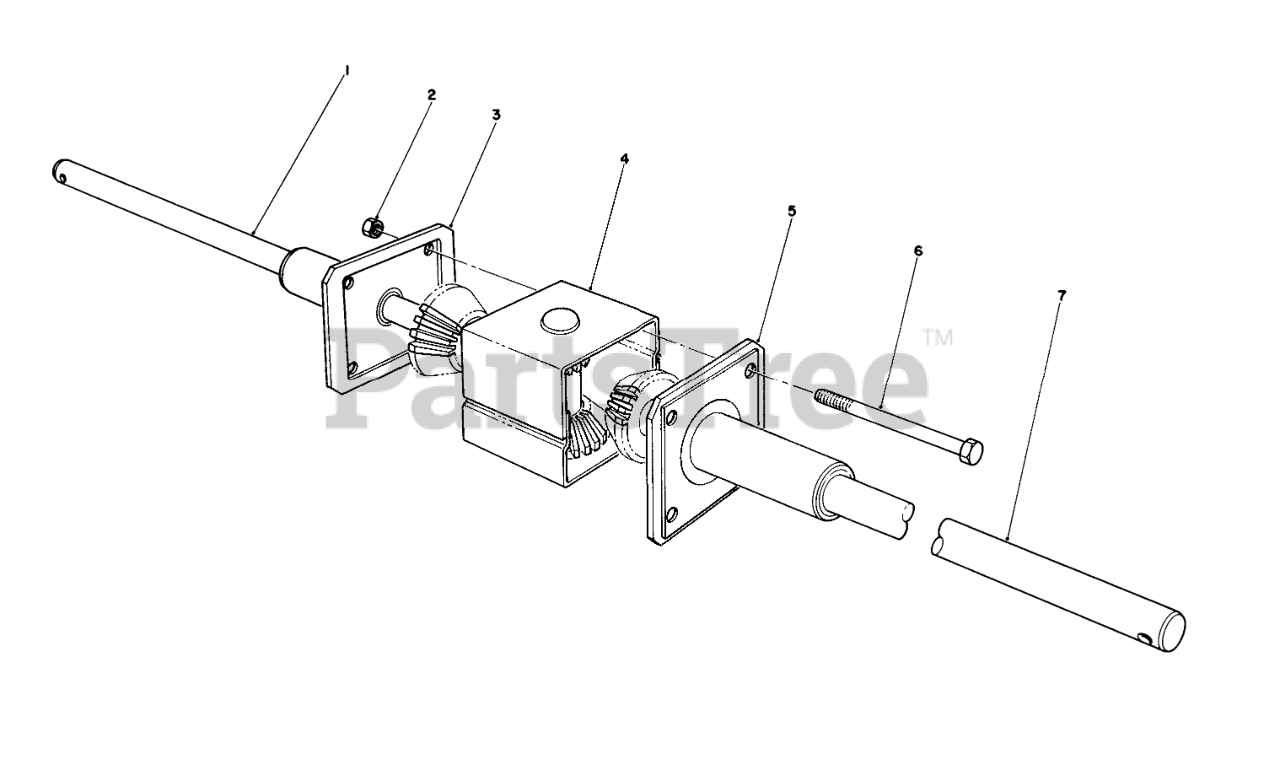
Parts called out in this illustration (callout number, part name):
2	NUT-LOCK, CONE
3	END CAP/BRG ASM
4	GEAR CASE ASM
5	END CAP &BEARING ASY
6	SCREW-HH
